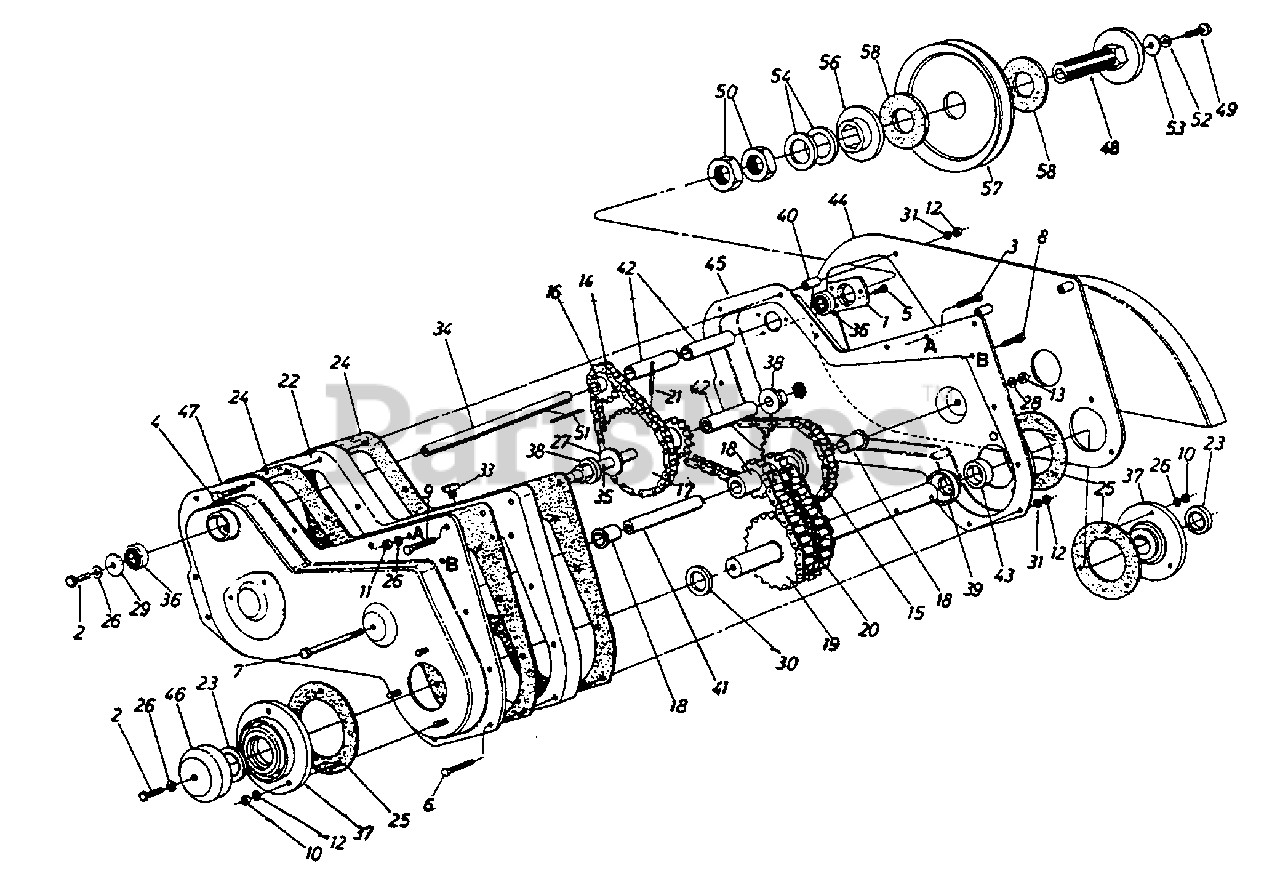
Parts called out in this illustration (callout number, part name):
1	Bearing Housing 1-3/8" Dia.
2	Hex Bolt 5/16-18 x .8" (Spec.)
3	Hex Bolt 5/16-18 x 1.5" Lg.
4	Hex Bolt 1/4-20 x 2.75" Lg.
5	Hex S-Tap Scr. 1/4-20 x .5" Lg.
6	Hex Bolt 1/4-20 x 1.5" Lg.
7	Hex Bolt 3/8-16 x 4.5" Lg.
8	Hex Scr. 1/4-20 x 1.5" Lg.
9	Hex TT-Tap Scr. 5/16-18 x 1.75"
10	Hex L-Nut 5/16-18 Thd.
11	Hex Nut 5/16-18 Thd.
12	Hex Nut 1/4-20 Thd.
13	Hex Nut 3/8-16 Thd.
14	#41 Chain 1/2" Pitch x 34 Links-Endless
15	#42 Chain 1/2" Pitch x 48 Links-Endless
16	Sprocket 10 Tooth .5" Pitch
17	10 & 28 Teeth Sprocket Ass'y.
18	8-2 & 28 Sprocket Sleeve Ass'y.
19	18-2 Sprocket Shaft Ass'y.
20	#50-2 Chain 5/8" Pitch x 28 Links-Endless
21	Spring Pin Spir. 1/4" Dia. x 1.5" Lg.
22	Spacer Block-Tiller Housing
23	Oil Seal 1-1/4" Dia.
24	Gasket for Tiller Housing
25	Gasket for Brg. Housing
26	L-Wash. 5/16" I.D.
27	Fl-Wash. .64" I.D. x 1.24" O.D.
28	L-Wash. 3/8" I.D-H.D.
29	Fl-Wash. .344" I.D. x 1.125"
30	Special Washer
31	L-Wash. 1/4" I.D.
33	Vent Plug
34	Jack Shaft .525" I.D. x 7.78"
35	Sprocket Shaft .63" Dia. x 5"
36	Ball Brg. .62" I.D. x 1.38" O.D.
37	Bearing Housing-1.1/4"
38	Hex Flange Brg.
39	Spacer 1.25" I.D. x 2.0" O.D.
40	Spacer .9" Lg.
41	Spacer 3.44" Lg.
42	Spacer .62" x
43	Spacer .5" Lg.
46	Dust Cap
49	Hex Bolt 5/16-18 x 1.25" Lg. Grade 5
50	Hex Jam Nut 1.0-14 x 28 Thd.
51	Sq. Key 3/16 x 1.5" Lg.
52	L-Wash. 5/16" I.D.
53	Fl-Wash. .344" I.D. x 1.125"
54	Bell-Wash. 1.0" I.D. x 2.0"
56	Floating Disc 3-1/4" O.D.
57	5/8 V-Pulley 1.5" I.D. x 6.5"
58	Friction Pad 3-1/4" O.D. x 1-3/8" I.D.
